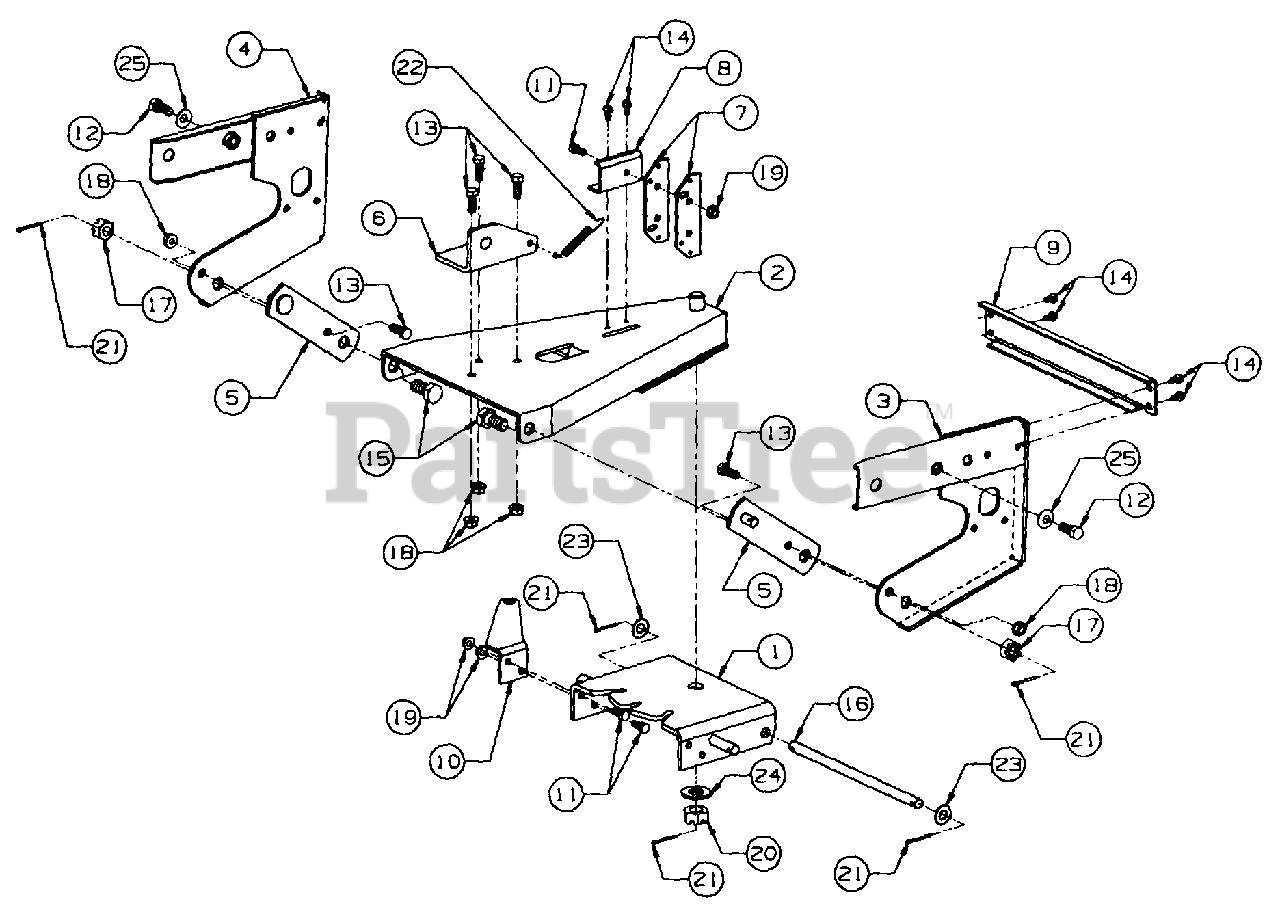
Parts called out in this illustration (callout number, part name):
1	Pivot Assy, Blade
2	A-Frame, Blade
3	Hitch, Blade - RH
4	Hitch, Blade - LH
5	Arm, Mounting
6	Bracket, Front Lift
7	Plate, Blade Angle Latch
8	Bracket, Latch Pivot
9	Bracket, Blade Support
10	Arm, Blade Angle
11	Screw, Hex Cap, 5/16-18 X .75 Lg
12	Screw, Hex Cap, 7/16-14 X 1.0 Lg
13	Screw, Hex Cap, 3/8-16 X 1.0 Lg GR5
14	Screw, Hex Wash Hd Tapp, 1/4-20 X .50 Lg
15	Screw, Hex Cap, 5/8-18 X 1.25 Lg GR5
16	Rod, Blade Pivot, .50 Dia X 10.22 Lg
17	Nut, Hex Slotted, 5/8-18
18	Nut, Hex Flanged Lock, 3/8-16
19	Nut, Hex Flange Top Lock, 5/16-18
20	Nut, Hex Slotted, 3/4-16 GR5
21	Pin, Cotter, 1/8 Dia X 1.25 Lg
22	Spring, Extension, .38 OD X 3.25 Lg
23	Washer, Flat, .510 X 1.0 X .06 Thk
24	Washer, Flat, .750 X 1.50 X .120 Thk
25	Washer, Bell, .45 X 1.0 X .062 Thk
